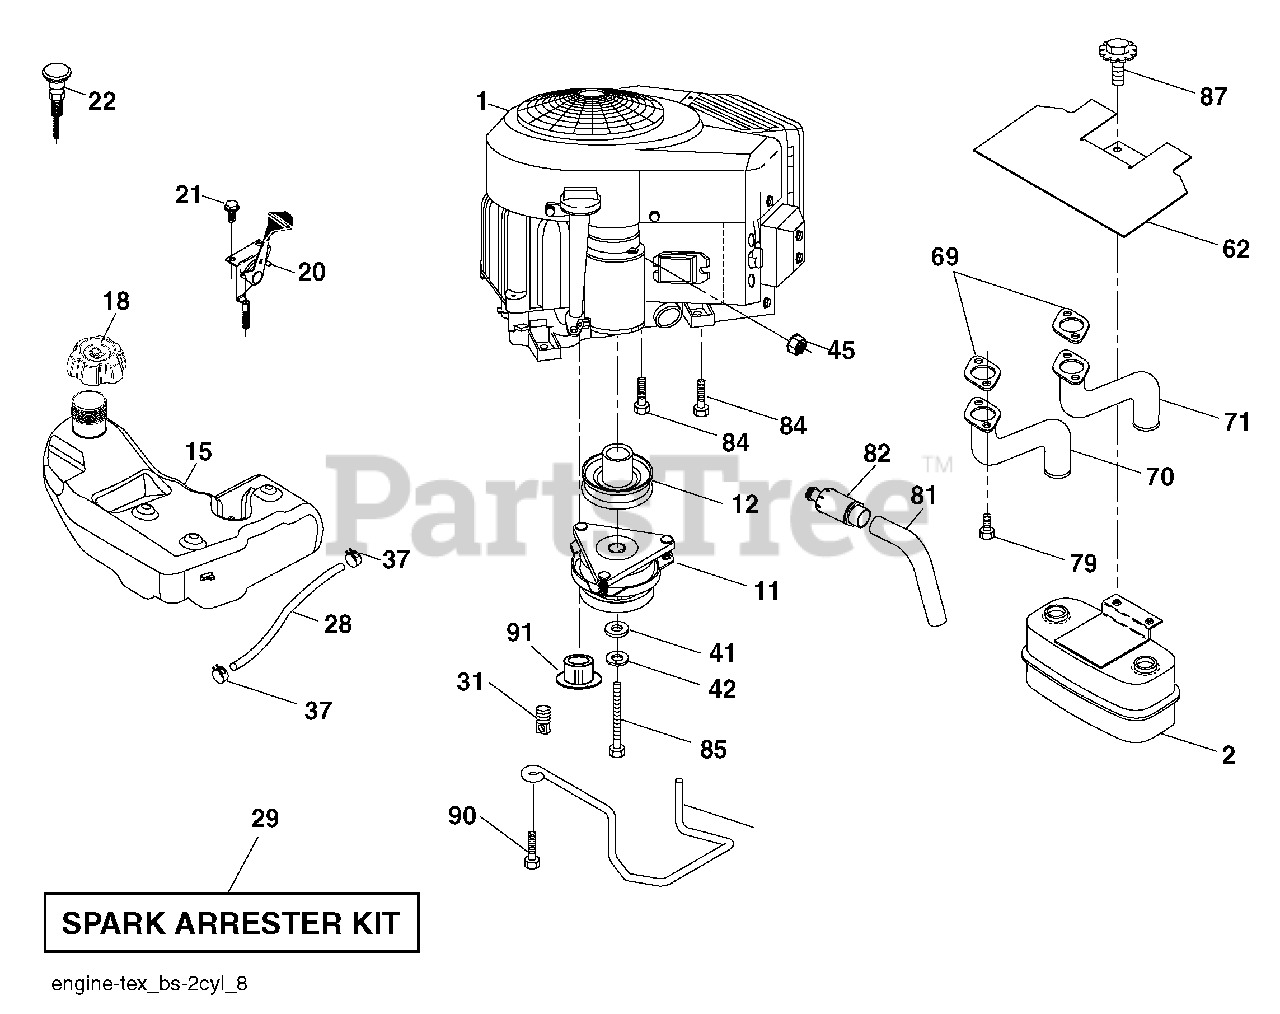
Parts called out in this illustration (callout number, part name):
2	Muffler
9	Keeper Belt Engine
11	Clutch Electric
12	Pulley Engine
15	Tank Fuel
18	Cap Asm.
20	Control Throttle
21	Screw #10 x 0.750 BOS Thread
22	Control Choke
28	Fuel Line
29	Spark Arrester Kit
31	Clip Push-In Hinged
37	Clamp Hose
41	Washer 1-1/2 OD x 15/32 ID x .250
42	Washer Lock 7/16
45	Nut Keps Hex 1/4-20 unc
62	Shield Heat Muffler
69	Gasket
70	Exhaust Tube LH
71	Exhaust Tube RH
79	Screw Socket Head 5/16-18 x 1
81	Tube Drain Oil Easy
82	Plug Drain Oil
84	Screw 3/8-16 x 1-1/4
85	Bolt Hex 7/16-20 x 3.75 Gr. 5
87	Bolt 5/16-18 x 1
90	Screw 3/8-16 x 1
91	Bushing 1.375 OD
